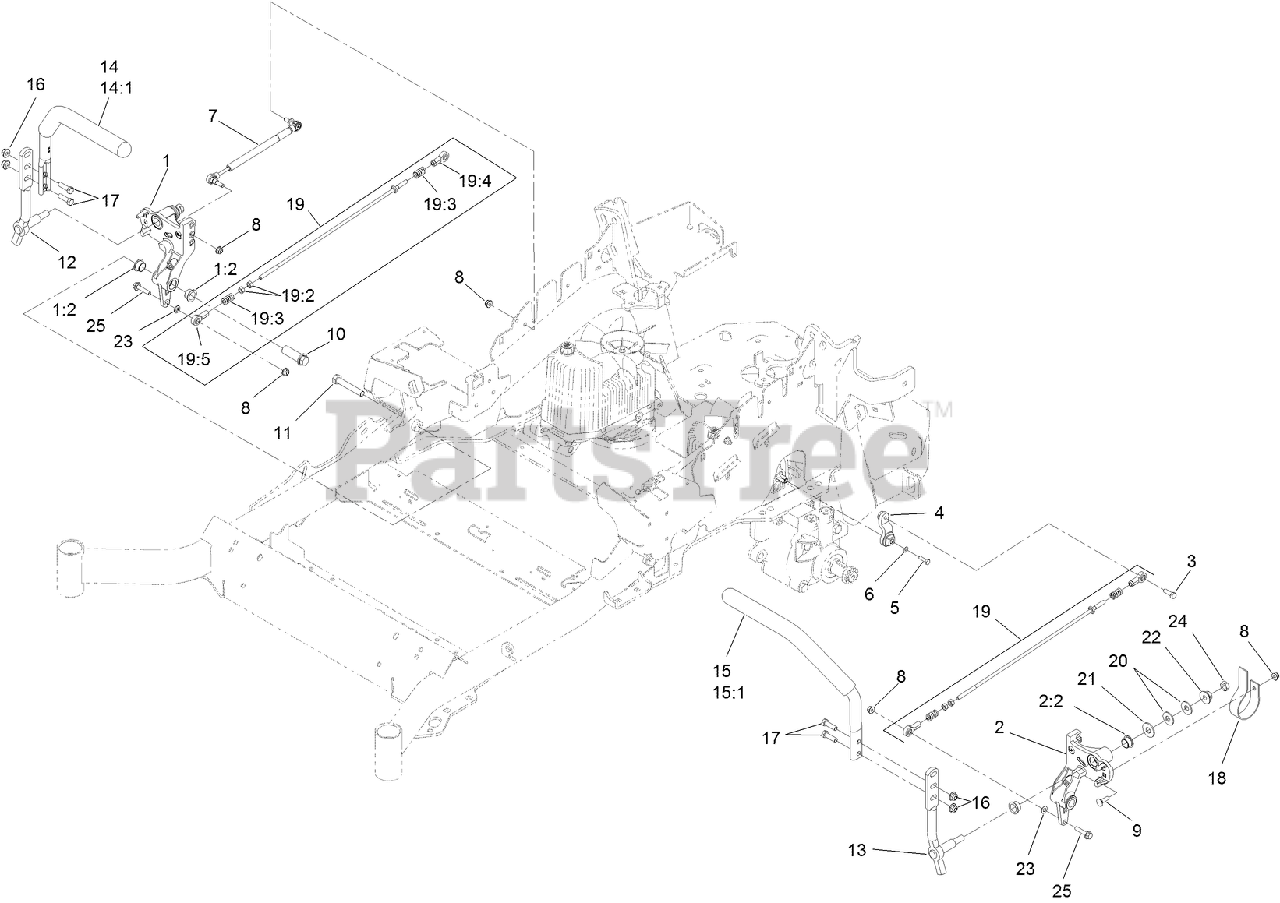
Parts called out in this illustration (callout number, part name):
1	RH MOTION CONTROL AND BUSHING ASM
1:2	BUSHING-FLANGE
2	LH MOTION CONTROL AND BUSHING ASM
2:2	BUSHING-FLANGE
3	SCREW-HH, THREAD LOCKING
4	ARM-CONTROL, PUMP
5	SCREW-HH
6	WASHER-SPRING
7	DAMPER-CONTROL, MOTION
8	NUT-HF, NI
9	BOLT-CARR
10	HUB-THREADED
11	SCREW-HH
12	LEVER-CONTROL MOTION, RH
13	LEVER-CONTROL MOTION, LH
14	RH STEERING HANDLE ASM
14:1	GRIP-CONTROL, LEVER
15	LH STEERING HANDLE ASM
15:1	GRIP-CONTROL, LEVER
16	NUT-HF, NI
17	SCREW-HH
18	SPRING-LEAF
19	FRONT PUMP LINKAGE ASM
19:2	NUT-HEX
19:3	SPRING-COMPRESSION
19:4	BALLJOINT-LH
19:5	BALLJOINT-RH
20	WASHER-SPRING
21	WASHER-FLAT
22	NUT-HF
23	WASHER-PLAIN
24	NUT-JAM
25	SCREW-HHF
